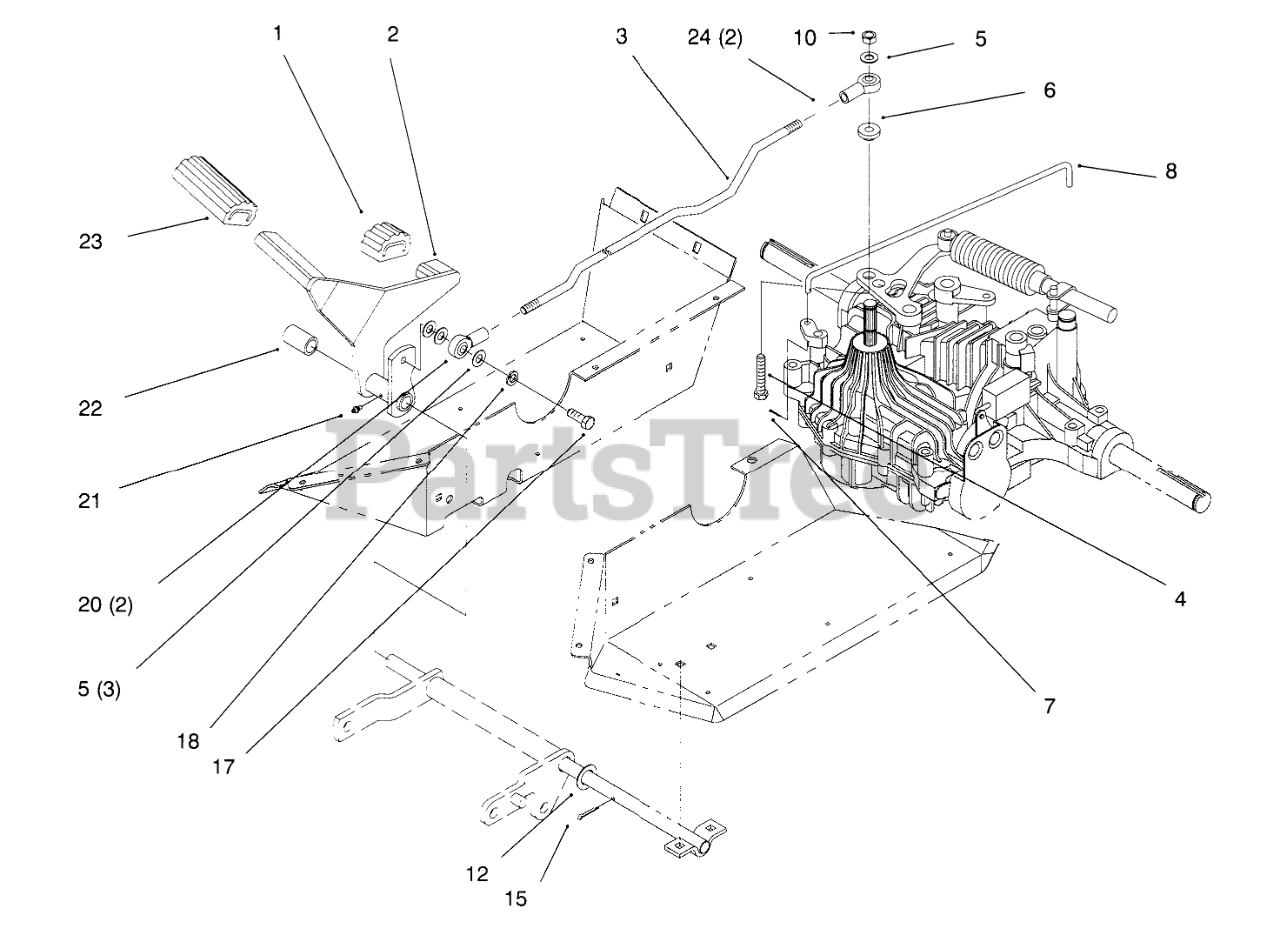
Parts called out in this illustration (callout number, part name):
1	PAD-PEDAL
2	PEDAL-HYDRO WA
3	ROD - HYDRO
4	SCREW-HH
5	WASHER-FLAT
6	BUSHING
7	PIN-COTTER
8	ROD - BYPASS
10	NUT-LOCK, NI
12	WASHER-FLAT
15	PIN-COTTER
17	SCREW-HH
18	WASHER-LOCK
20	END-ROD, FEMALE
21	FITTING-GREASE
22	SPACER
23	PAD-PEDAL
24	NUT-HJ
